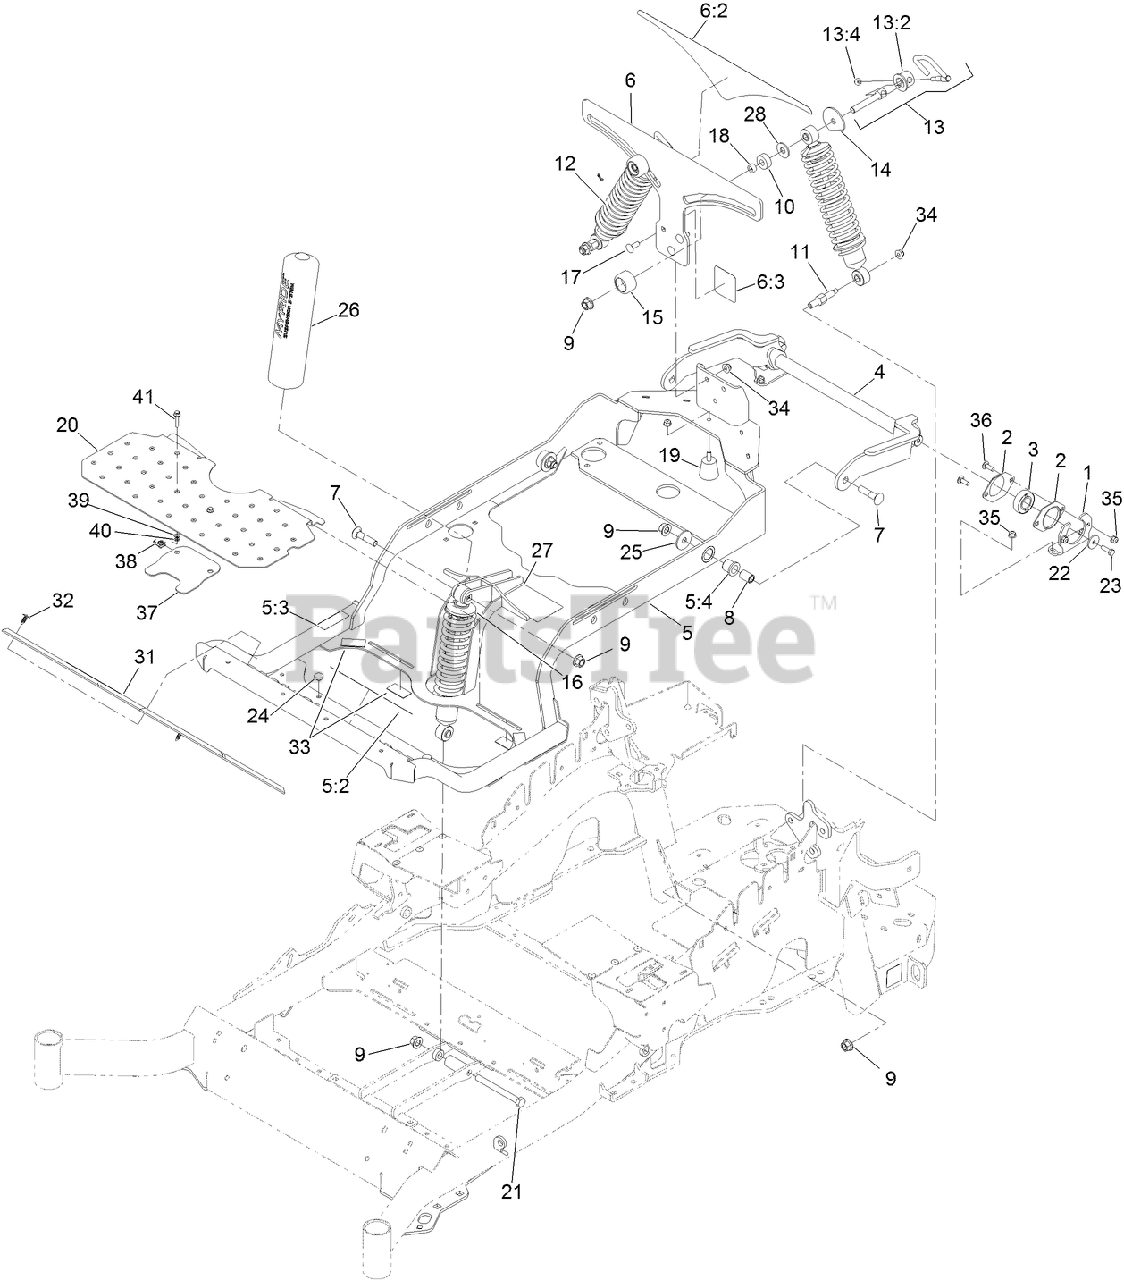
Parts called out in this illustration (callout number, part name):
1	BRACKET-BEARING
2	HOUSING-BEARING, FLANGE
3	BEARING
4	ARM-TRAILING
5	SUBFRAME ASM
5:2	DECAL-DANGER
5:3	DECAL-BRAKE, PARKING
5:4	BUSHING-FLANGE
6	BRACKET-MOUNTING
6:2	DECAL-ADJUSTMENT, RIDE
6:3	DECAL-LOCK, CAM
7	SCREW-CARR
8	SPACER-ALUMINUM
9	NUT-LOCK
10	SPACER
11	BOLT-SHOULDER
12	SHOCK/SPRING ASM
13	CAM LOCK ASM
13:2	CAP-LOCK
13:4	NUT-HEX
14	PLATE-STOP
15	KNOB-FRONT
16	SHOCK ASM-FRONT
16	SHOCK/SPRING ASM
17	SCREW-CARR
18	BEARING-NEEDLE
19	BUMPER-RUBBER
20	FLOORPAN
21	SCREW-HH
22	WASHER-FLAT
23	SCREW-HH, THREAD LOCKING
24	BUMPER
25	WASHER-THRUST
26	COVER-SHOCK
27	DECAL-SERVICE AID
28	WASHER-FLAT
31	MAT-FLOOR
32	PLUG-PLASTIC
33	PAD-RUBBER
34	NUT-HF, NI
35	NUT-HF, NI
36	BOLT-CARR
37	ADAPTER-CAPTIVE
39	WASHER-FLAT
40	NUT-RETAINER
41	SCREW-HHF
